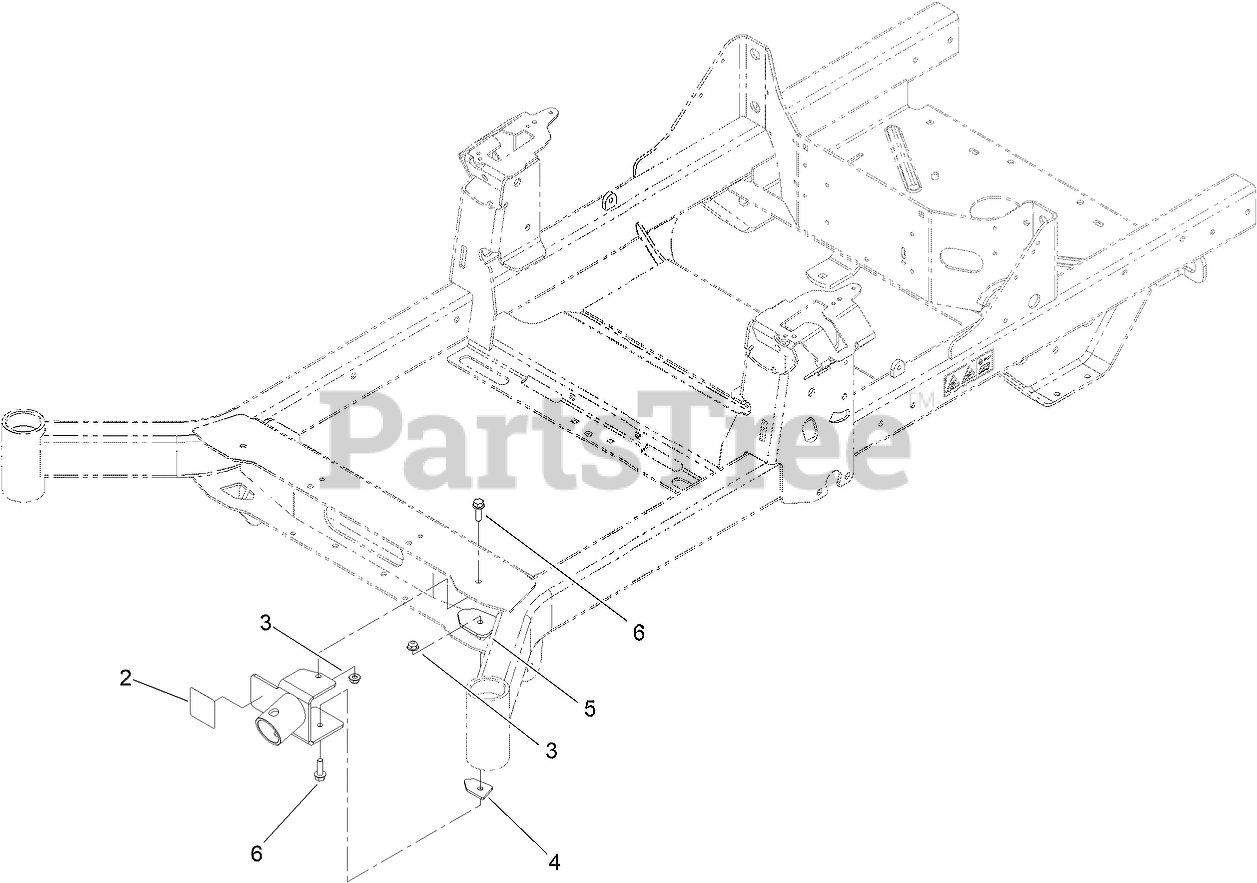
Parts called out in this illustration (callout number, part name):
2	DECAL-WARNING, JACK
3	NUT-HF
4	PLATE-PILOT, JACK MOUNT
5	PLATE-BACKER
6	SCREW-HHF
